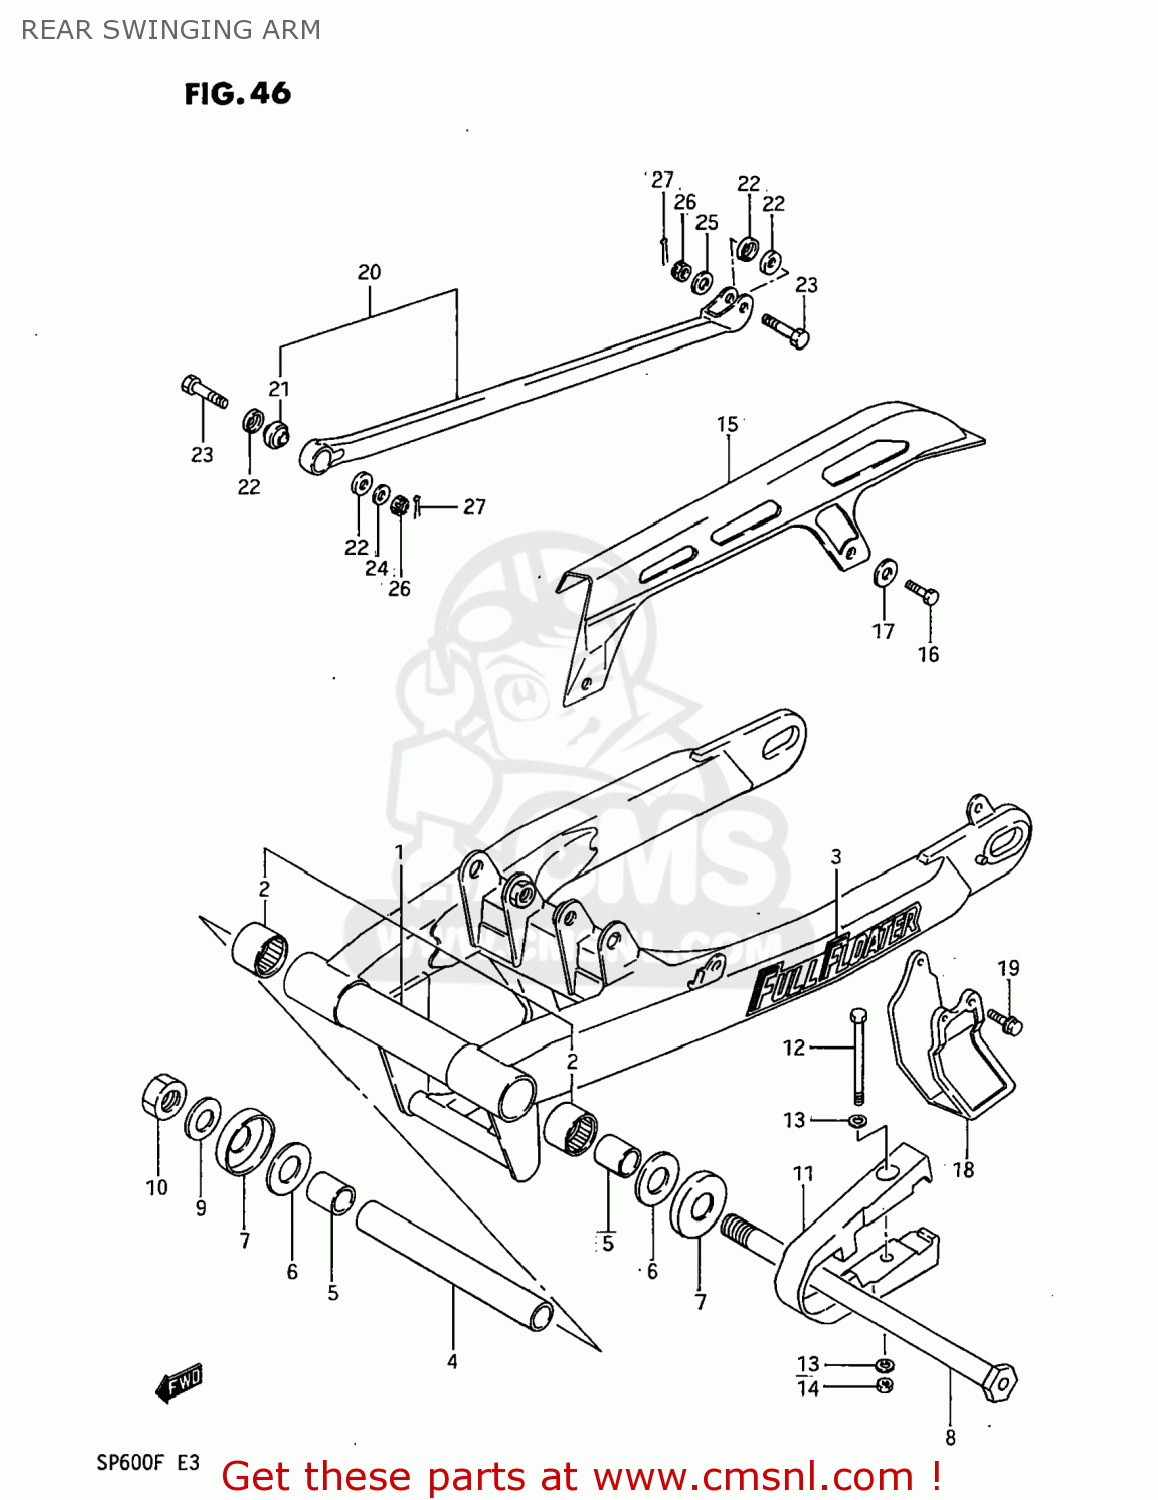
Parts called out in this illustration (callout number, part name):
1	SWING ARM ASSEMBLY,REAR
2	BEARING(22X29X20)
3	EMBLEM,SWING ARM
4	SPACER,RR SWGARM PIVOT CTR
5	SPACER,RR SWGARM PIVOT
6	WASHER
7	SEAL,RR SWGARM PIVOT DUST
8	SHAFT,RR SWINGINGARM PIVOT
9	WASHER
10	NUT 16MM
11	BUFFER,CHAIN TOUCH DEFENSE
12	BOLT,TOUCH DEFENSE FTG
13	WASHER(5.2X16X1)
14	NUT
15	CASE,CHAIN
16	BOLT
17	WASHER
18	GUIDE,CHAIN
19	BOLT
20	LINK,REAR TORQUE
21	SPHERICAL BEARING,TORQUE
22	23
23	BOLT 8X32
24	WASHER
25	WASHER
26	NUT 8MM
27	PIN 20X20
